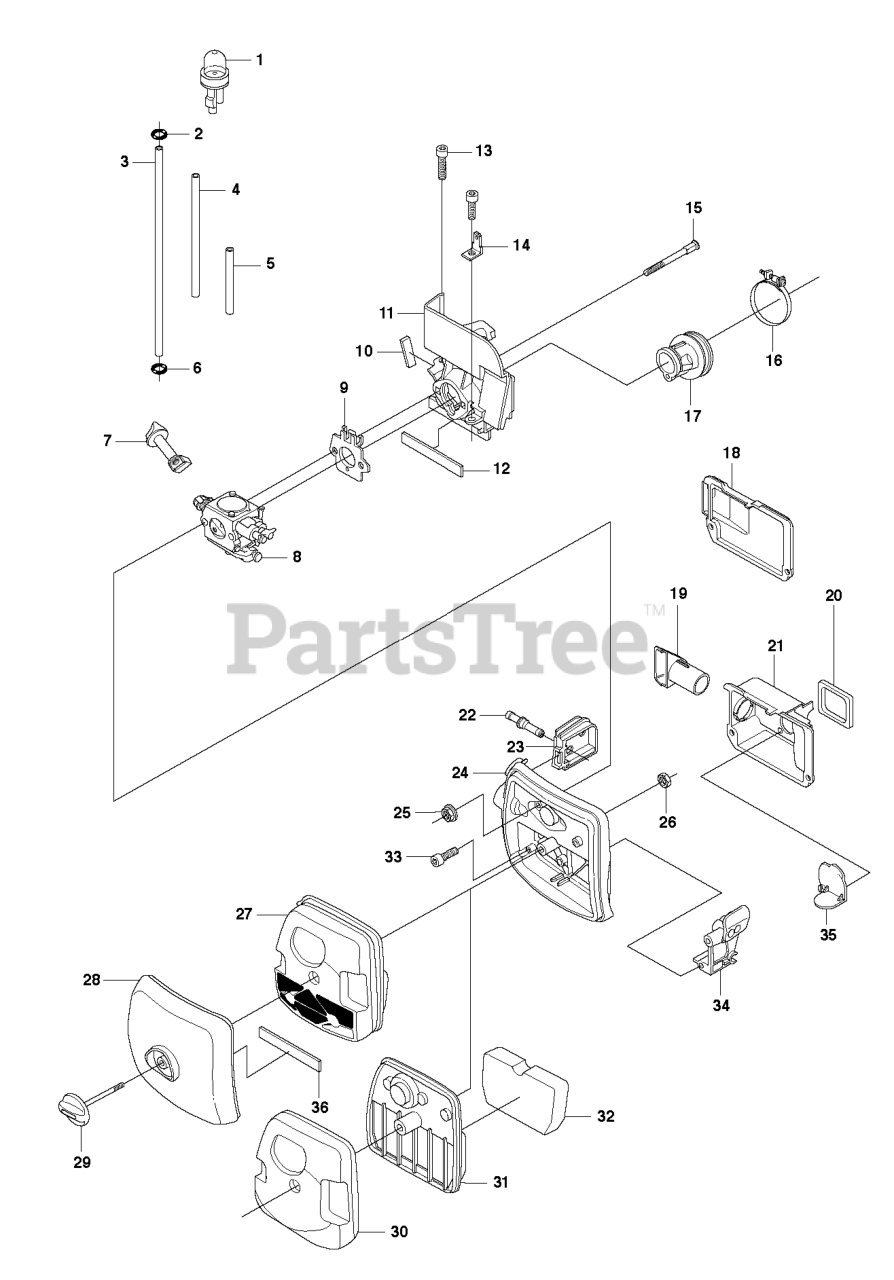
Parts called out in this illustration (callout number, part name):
1	AIR PURGE BUBBLE
3	FUEL HOSE
4	HOSE.FUEL L=102
5	NOSE
7	CHOKE CONTROL
8	CARBURETOR
9	SPACER WASHER
16	CLAMP
18	COVER
19	AIR CONDUCTOR
20	SEAL
21	AIR CAN
24	FILTER HOLDER
26	NUT M6M M5
27	AIR FILTER
28	RP FILTER COVER COMP
29	HANDLE AIR FILTER COVER
30	COVER
31	BASE
32	AIR FILTER
34	SCREW DRIVER GUIDE
35	COVER
